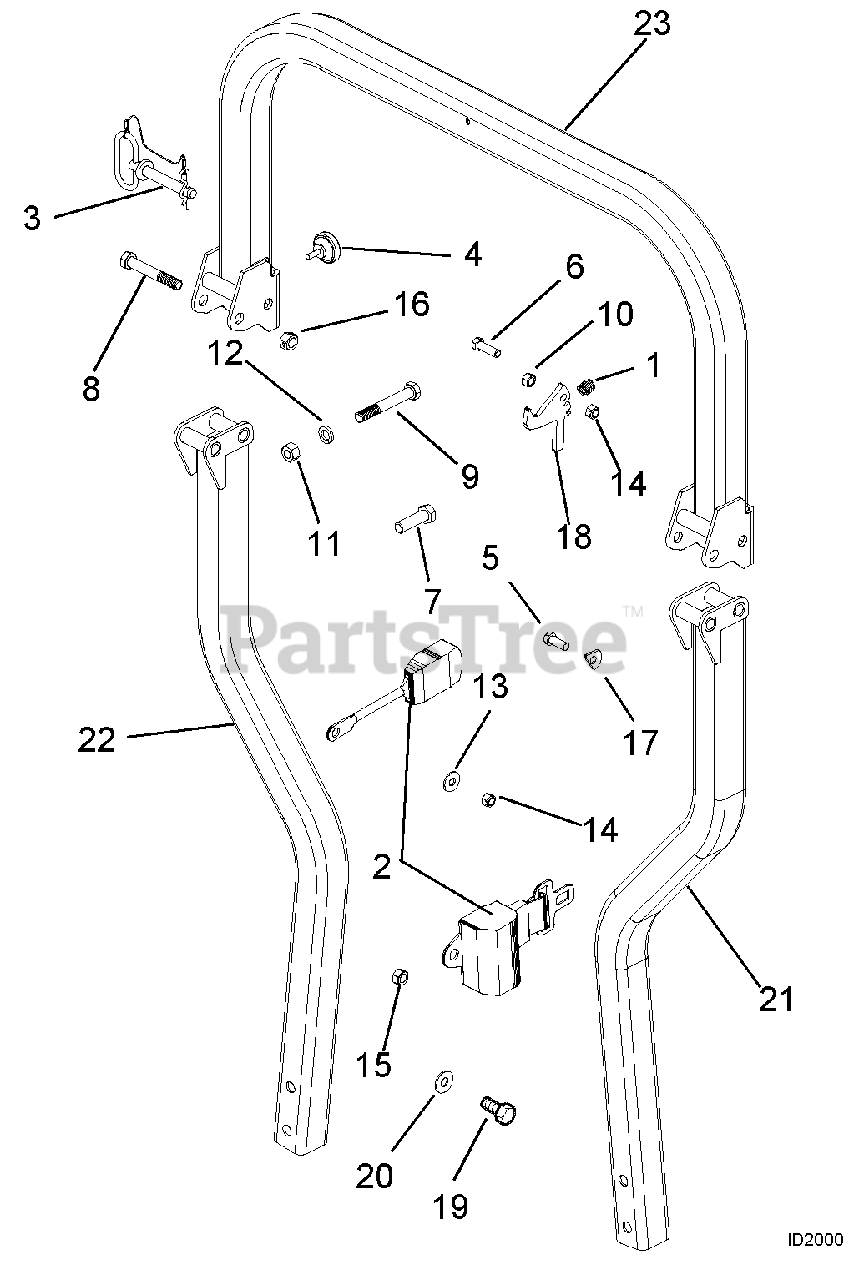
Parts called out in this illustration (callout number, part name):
1	SPRING, COM .600X.056X.875 Y
2	ASSY, SEAT BELT
3	ASSY, ROPS LOCK PIN S/O
4	KNOB, ROUND 5/16-18 X .750
5	@BLT-HEX .38-16X1.25 GR5 YWZC
6	BOLT, 3/8-16X1.25 HEX 5 Y
7	BOLT, 7/16-14X1.00 HEX 5 Y
8	BOLT, 5/16-18X.500 HEX 5 Y
9	BOLT, 5/16-18X.750 HEX 5 Y
10	NUT, 3/8-16 STD HEX GR5 Y
11	NUT, 1/2-13 STD HEX GR5 Y
12	WASHER, .500 MED SPRG LOCK Y
13	WASHER, .375 REG FLAT Y
14	LOCKNUT, 3/8-16 CROWN Y
15	LOCKNUT, 7/16-14 CROWN Y
16	LOCKNUT, 1/2-13 CENTER Y
17	WASHER, SEAT BELT Y
18	LATCH, SEAT
19	@BLT-HEX .44-20X.75 GR5 YWZC
20	WASHER, .438 MED SPRG LOCK Y
21	Right Side Base Weldment
22	Left Side Base Weldment
23	Center Tube Weldment
